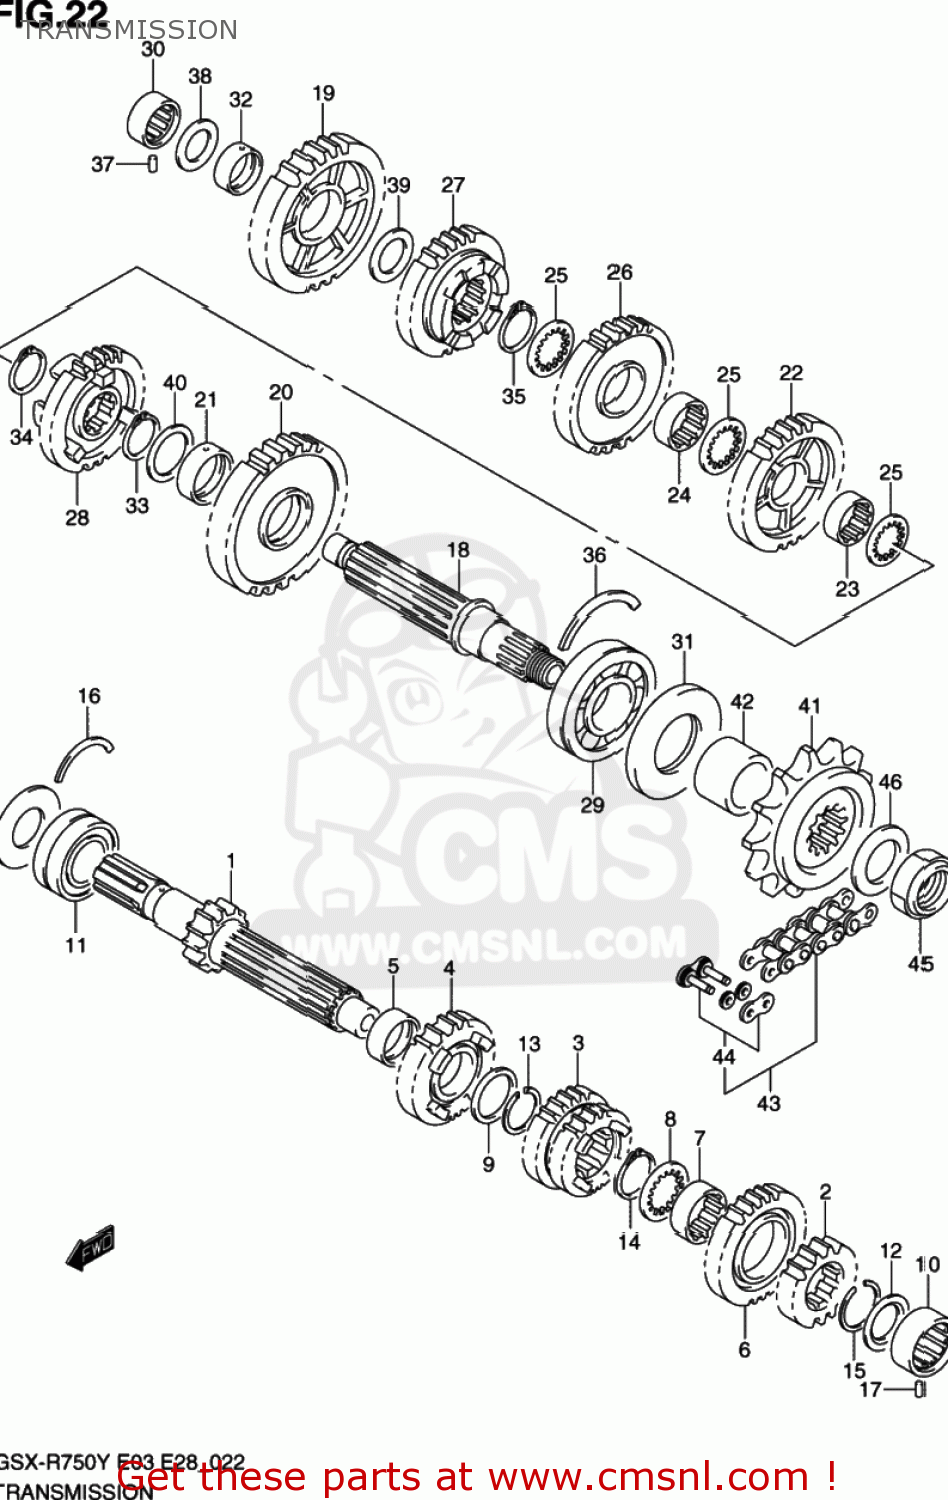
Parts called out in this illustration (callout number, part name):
1	SHAFT,COUNTER
2	GEAR,2ND DRIVE
3	GEAR,THIRD & FOURTH DRIVE
4	GEAR,FIFTH DRIVE
5	BUSH,5TH DRIVE GEAR
6	GEAR,SIXTH DRIVE
7	BUSH,6TH DRIVE GEAR
8	WASHER,LOCK
9	SHIM(27X36X2.5)
10	BEARING(20X34X13.5)
11	BEARING(25X52X20.6)
12	SEAL,OIL(20X31.2X2.7)
13	CIRCLIP
14	CIRCLIP
15	CIRCLIP
16	C RING
17	PIN(6X10)
18	SHAFT,DRIVE
19	GEAR,FIRST DRIVEN
20	GEAR,2ND DRIVEN
21	BUSH,2ND DRIVEN GEAR
22	GEAR,3RD DRIVEN
23	BUSH,3RD DRIVEN GEAR
24	BUSH,3RD DRIVEN GEAR
25	WASHER,3RD & 4TH DRIVEN
26	GEAR,4TH DRIVEN
27	GEAR,5TH DRIVEN
28	GEAR,6TH DRIVEN
29	BEARING(28X70X18)
30	BEARING(20X34X13.5)
31	SEAL,OIL(34.8X70X6)
32	BUSH(22X26X9)
33	CIRCLIP
34	CIRCLIP
35	CIRCLIP
36	C RING
37	PIN(6X10)
38	SHIM(20X34X1)
39	SHIM(22X34X1)
40	WASHER(27X36X1)
41	SPROCKET,ENGINE(17T)
42	SPACER,ENGINE SPROCKET
43	CHAIN ASSEMBLY RK525R0Z4.1
44	JOINT SET,DRIVE CHAIN
45	NUT
46	WASHER(25X41X3)
